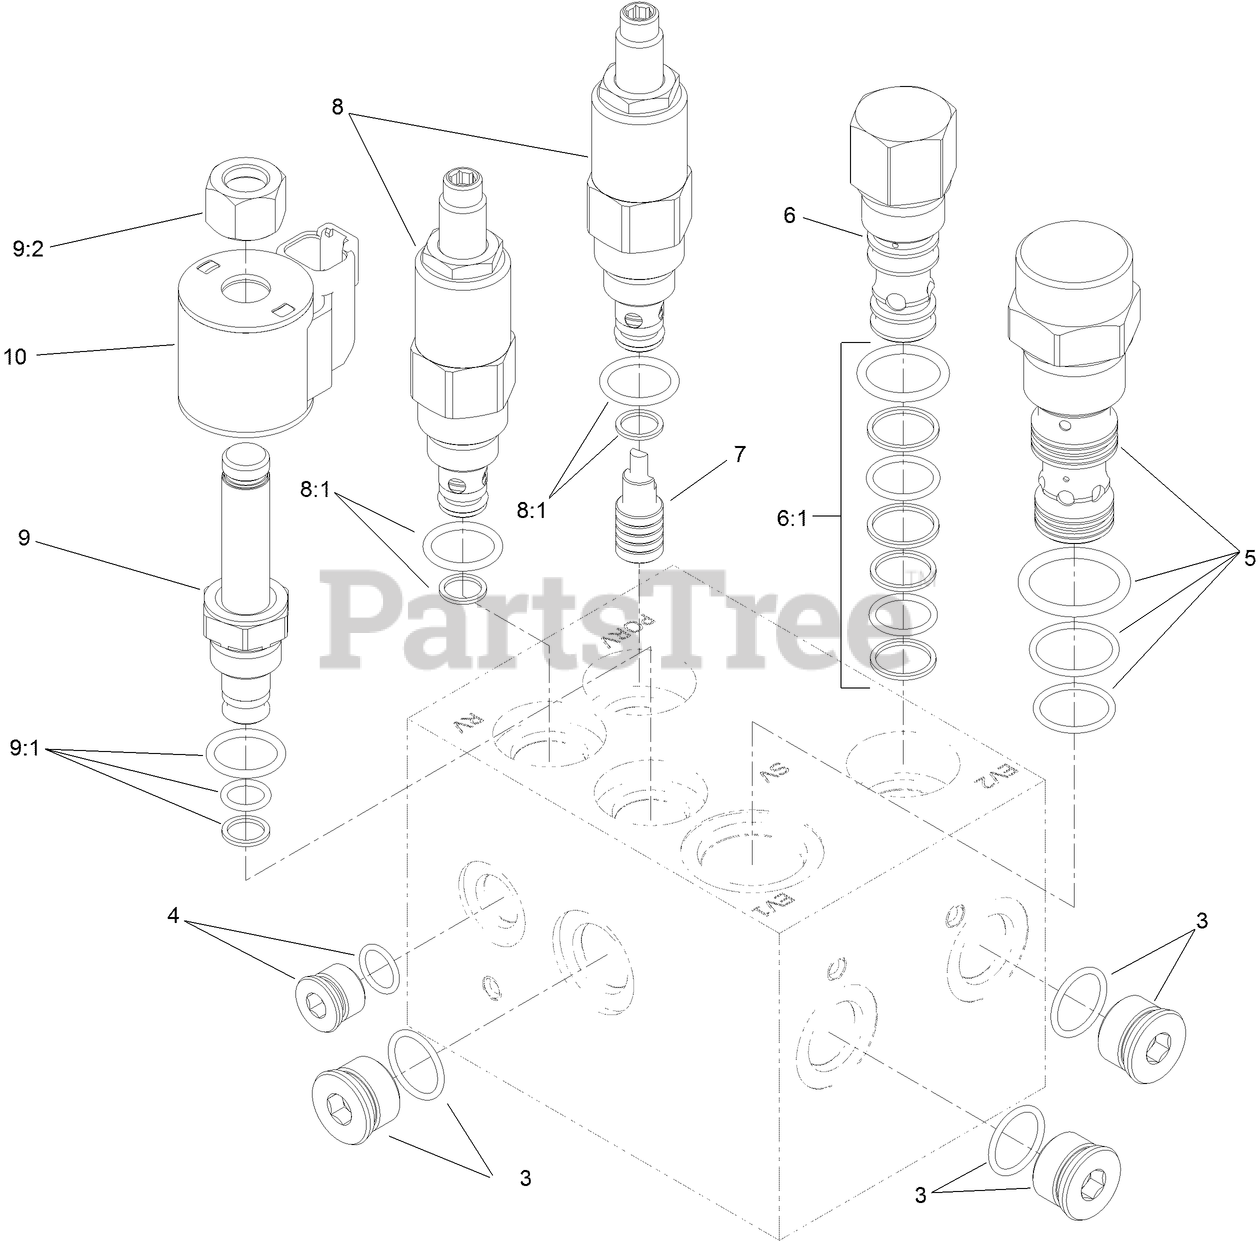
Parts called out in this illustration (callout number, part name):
3	PLUG
5	ELEMENT-LOGIC, VENTED
6	ELEMENT-LOGIC, VENTED
6:1	SEAL KIT
7	PISTON-PILOT
8	VALVE-RELIEF
8:1	SEAL KIT
9	VALVE-SOLENOID
9:1	SEAL KIT
9:2	NUT-SOLENOID
10	E COIL-12V DC
